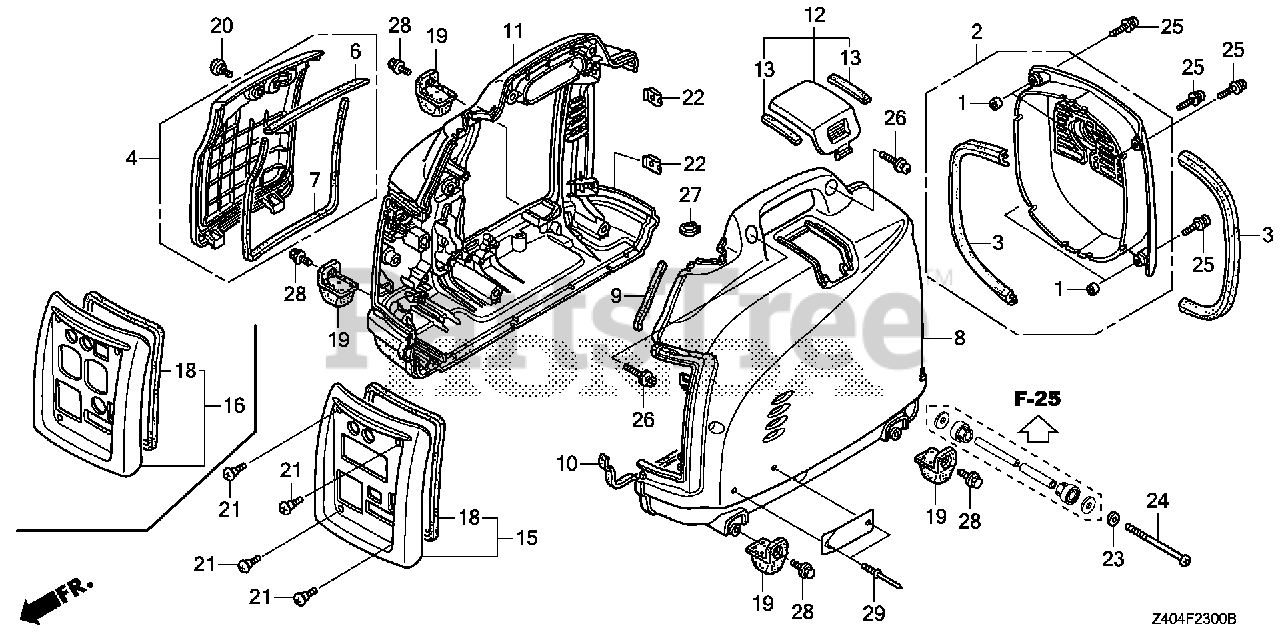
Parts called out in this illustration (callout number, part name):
1	COLLAR, CONTROL COVER
2	PROTECTOR, MUFFLER
3	SEAL RUBBER, PROTECTOR
4	COVER ASSY., MAINTENANCE
6	SEAL A, MAINTENANCE COVER
7	SEAL B, MAINTENANCE COVER
8	COVER, R. SIDE
9	SEAL A, SIDE COVER
10	SEAL B, SIDE COVER
11	COVER, L. SIDE
12	COVER ASSY., PLUG CHECK
13	SEAL, PLUG CHECK
15	COVER ASSY., FR.
18	SEAL, FR. COVER
19	RUBBER (LOWER)
20	SCREW, SPECIAL (6X16)
21	SCREW, FR. COVER
22	NUT, SPRING (5MM)
23	WASHER (6MM)
24	SCREW, PAN (6X100)
25	SCREW-WASHER (5X16)
26	SCREW-WASHER (6X20)
27	CIRCLIP (OUTER) (10MM)
28	BOLT, FLANGE (6X10)
